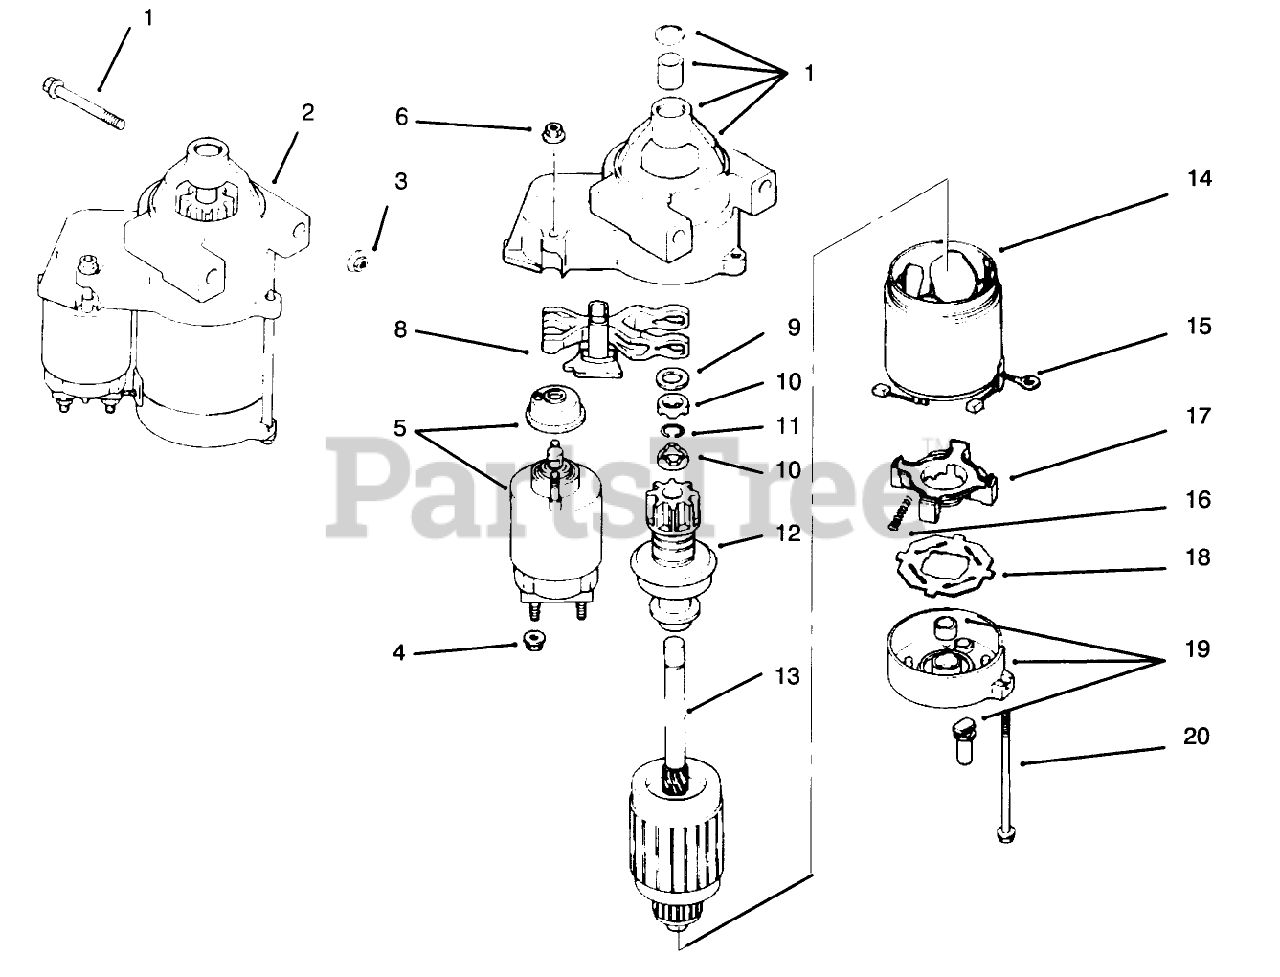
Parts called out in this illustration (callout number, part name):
1	Scew
2	Starter Solenoid Shift (Incl. Ref. #4-20)
3	Nut
4	Nut
5	Cap Drive End
6	Nut
7	Solenoid
8	Lever Starter Drive
9	Washer
10	Nut
11	Ring-Retainer
12	Drive Pinion
13	Armature
14	Frame
15	Kit-Brush (Incl. Ref. #16)
16	Spring Brush
17	Holder-Brush
18	Insulator
19	Cap-Commutator End
20	Bolt
